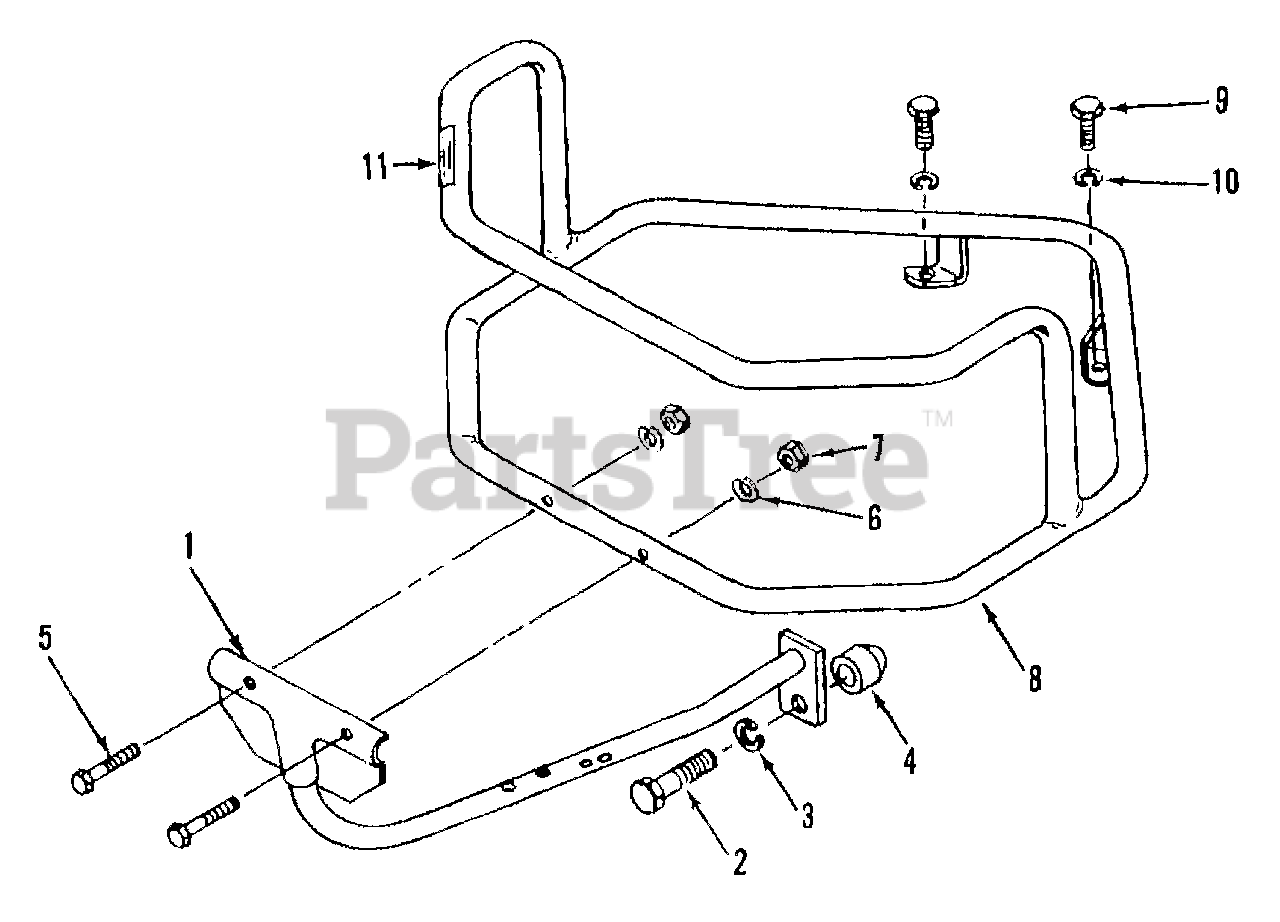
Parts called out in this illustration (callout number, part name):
1	BRACE-BUMPER BOTTOM PNT
2	SCR-HH 1/2-13X2.0 G5 ZP
3	WASHER-LK .5
4	SPACER-1X.531X1.125 ZP
5	SCR-HH 5/16-18X1.5 G5 ZP
6	WASHER-LK .312 ZP
7	NUT-HEX 5/16-18 ZP
9	SCR-HH 3/8-16X1.0 G5 ZP
10	WASHER-LK .375 @ DEPL
11	DECAL-BUMPER
